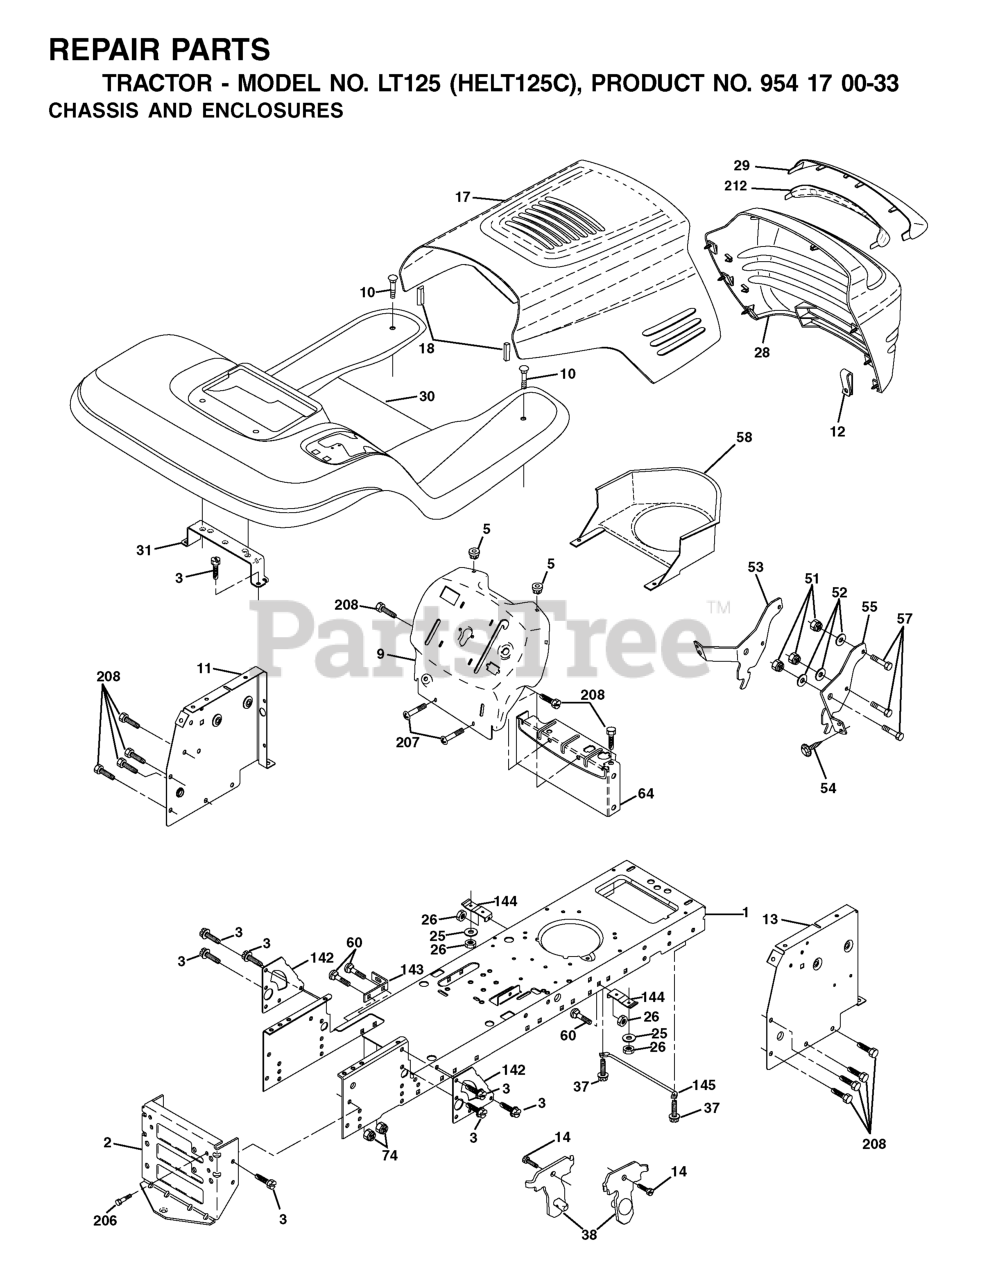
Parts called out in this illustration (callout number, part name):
1	CHASSIS STAMPING
2	DRAWBAR, 12GA
3	SCREW 3/8-16X3/4
5	BUMPER.RUBBER.HOOD
9	DASH
10	BOLT D
11	PANEL DASH LH
13	PANEL DASH RH
17	HOOD ASM.
18	BUMPER HOOD T
25	WASHER
26	NUT
28	GRILLE ASM
29	LENS
30	FENDER FOOTREST
31	BRACKET.SUPPORT.FENDER
37	Screw 5/16-18 x 1/2 Hex, Self Tapping 5/16-18 x 1/2
38	BRACKET.ASM.PIVOT.MOWER.REAR
51	LOCKNUT.NYLOC.1/4-20
53	BRACKET.GRILLE.LH
54	SCREW.HEX.WS.HD.8-18 X 7/8
57	BOLT
58	AIR DUCT P/L/LT
60	Bolt - Rd. Hd. Sq. Neckiage 3/8 16 x 3/4
64	DASH LOWER
142	PLATE REINFORCEMENT
143	BRACKET, SWAY BAR
144	BRKT, FOOT REST
145	ROD PIVOT CHASSIS/HOOD
206	SHOULDER BOLT 5/16-18TT
207	SCREW, 5/16-18 X 1/2
208	SCREW 3/8-16X1/2
212	REPL BY 532 1745-03
